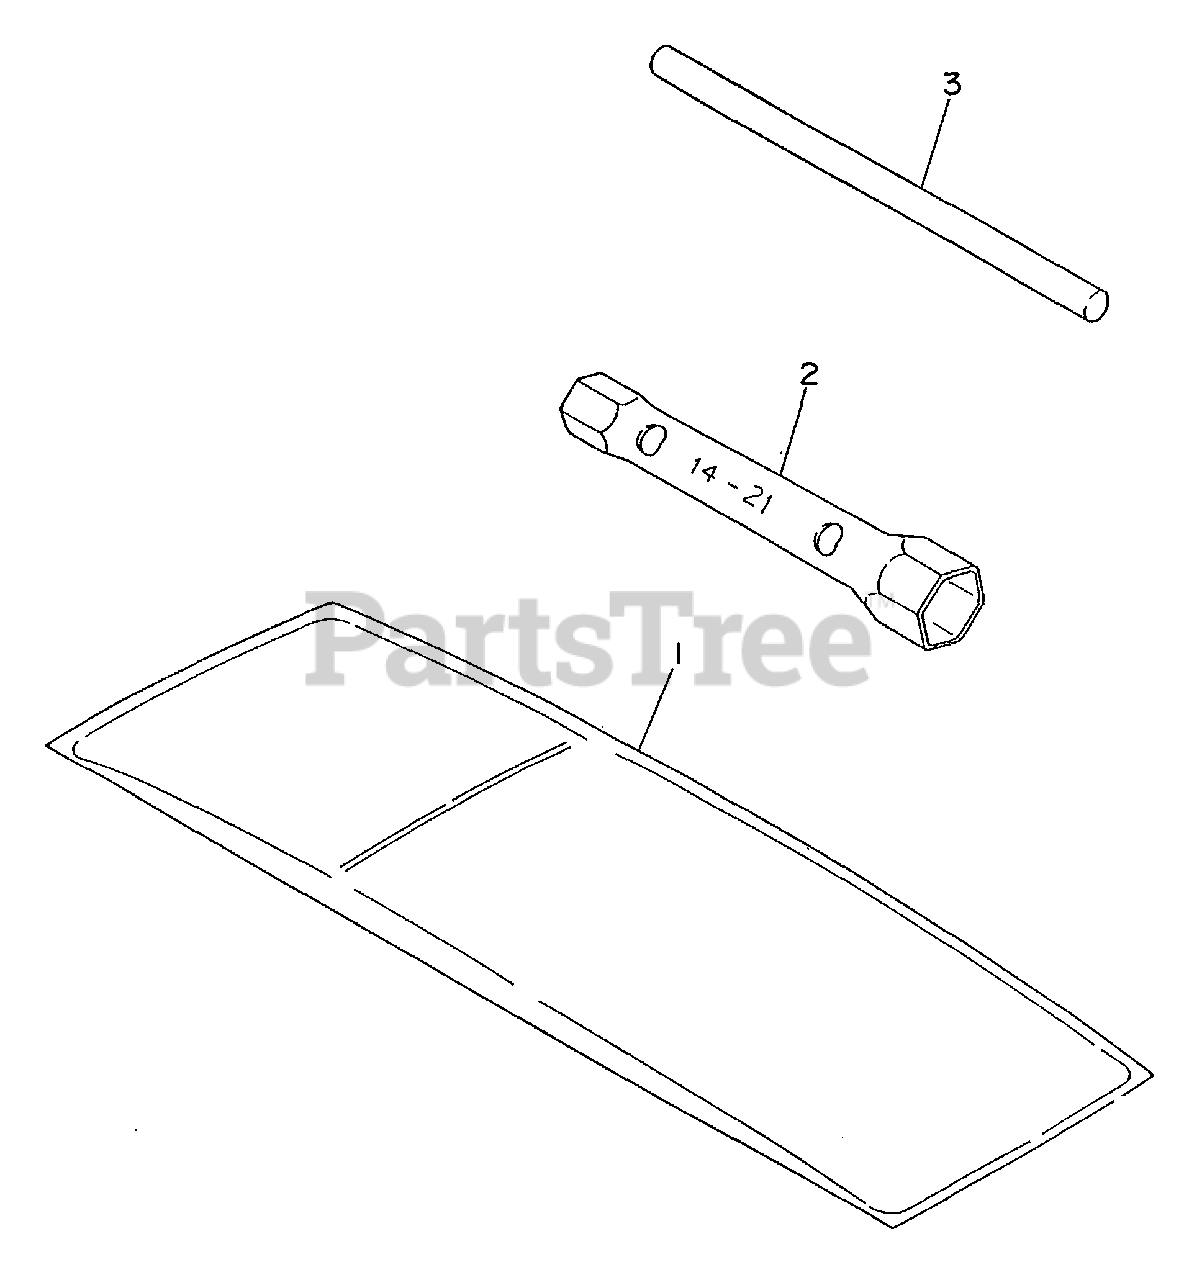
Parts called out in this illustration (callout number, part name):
1	TOOL KIT
2	See Ref. #1, ACCESSORY TOOLS KIT, P/N EY2279030100
3	See Ref. #1, ACCESSORY TOOLS KIT, P/N EY2279030100
